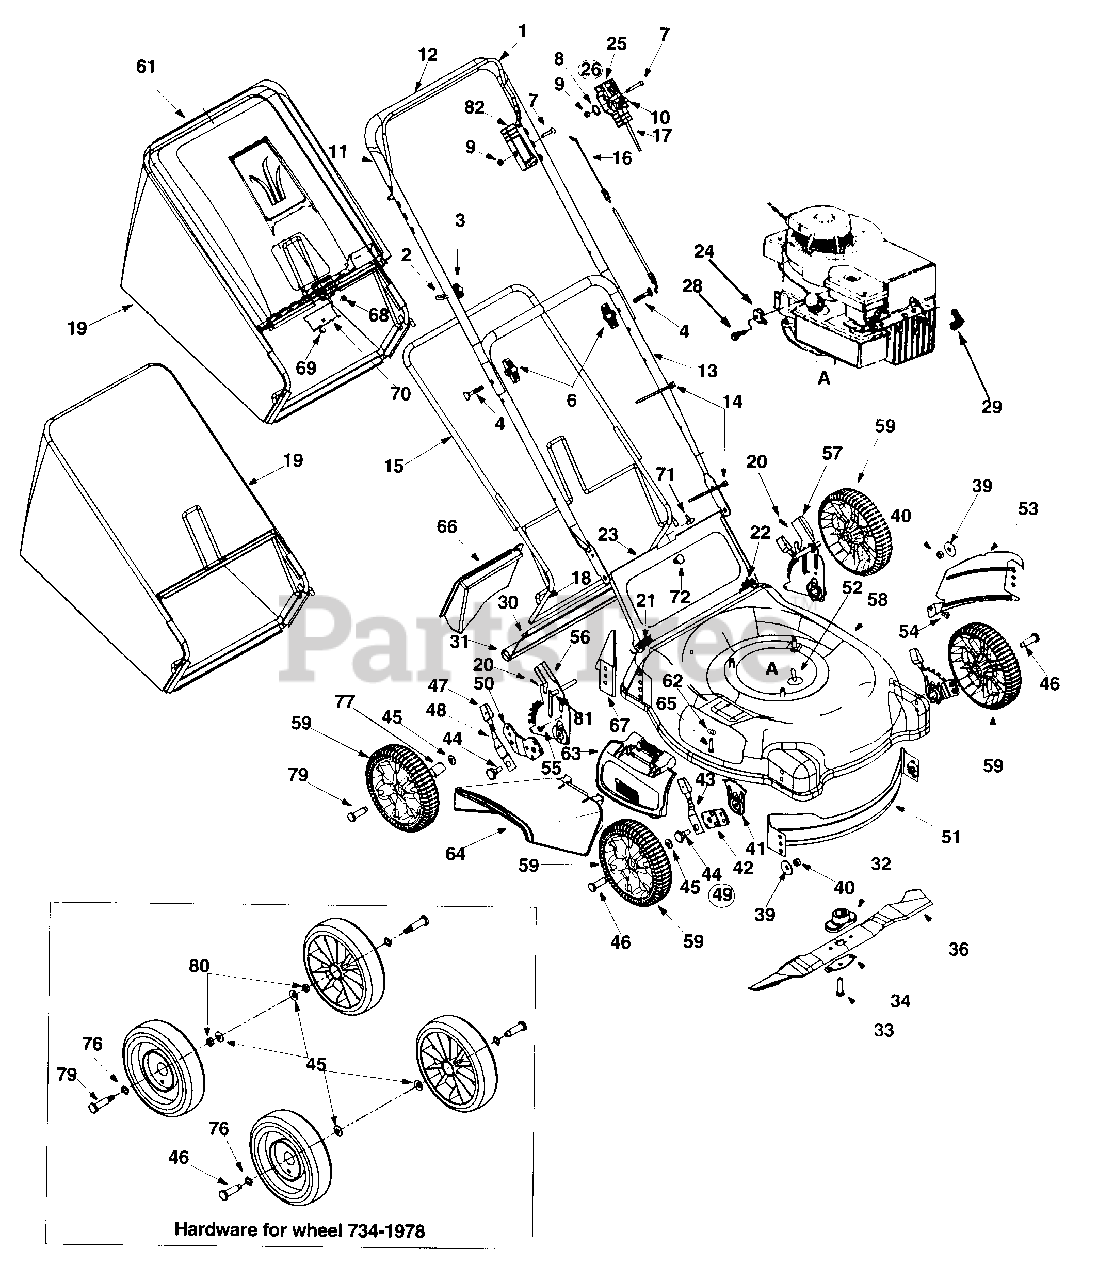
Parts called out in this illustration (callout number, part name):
2	Rope Guide
3	Handle Knob 1/4-20 Thd.
4	Curved Hd. Bolt 5/16-18 x 2" Lg.
6	Hand Knob
7	Oval C-Sunk Mach. Scr.
8	Spr. Wash..66" I.D.
9	Hex L-Nut 1/4-20 Thd
10	Throttle Lever
14	Cable Tie
16	Control Cable - 39"
17	Throttle Control Wire - 42"
20	Int. Cotter Pin 5/16" Dia.
21	Door Spring - R.H.
22	Door Spring - L.H.
25	Throttle Body
26	Thrott. Box
28	Hex Washer Scr. #10-32 x 62" (B&S)
29	Spark Plug Boot
30	Wire Rod
31	Rear Flap
32	Blade Adapter
33	Hex Bolt 3/8-24 x 1.5" Lg.
34	Blade Bell Support
36	21" Mulching Blade
39	Bell-Wash. .39" I.D. x 1.38"
40	Hex Nut 3/8-16 Thd.
41	Height Adj. Plate
43	Front Spring Lever Ass'y. w/Knob
44	Shld. Bolt .5" Dia. x .357"
45	Bell-Wash. .38" I.D. x .88" O.D.
46	Front Axle Bolt
47	Spring Lever Knob
48	Rear Spring Lever
49	Height Adj. Assy. Comp. - RH
50	Pivot Bar R.H.
54	Torx Mach AB-Tap Scr. 1/4 x.62"
55	HexInd Wash. Scr. 1/4-14:.625
56	Handle Brkt. Ass'y.- RH
57	Handle Brkt. Ass'y.- LH
61	Hard Top Cover w/ Icon
62	Bell-Washer 1/4" I.D.
63	Hinged Mulching Plug
64	Chute Deflector: Side Discharge
65	Hex Hd Self-Tp Scr. 1/4-20 x .5" L.
66	Mulching Baffle Plug
68	Pan Hd. Mach. Scr. 1/4-20:.5" Lg.
69	Hx. Nylon L-Nut - 1/4-20 Thread
71	Truss Scr. #10-24 x .38" Lg.
76	Wave Washer
79	Rear Axle Bolt
80	Spacer
81	Weld Pin
82	Throttle Housing w/o Lever
